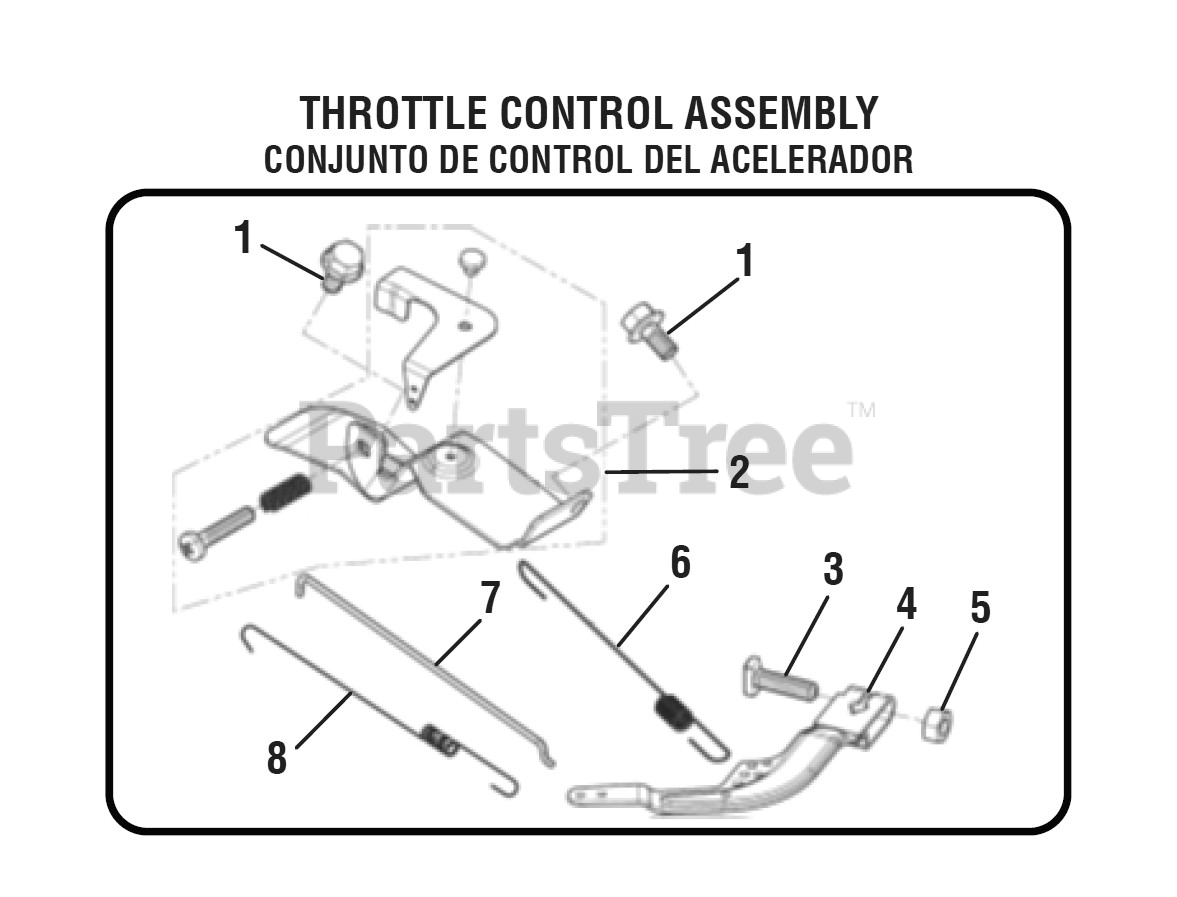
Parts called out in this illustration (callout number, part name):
2	Throttle Control Assembly
3	Governor Support Bolt
4	Governor Support Assembly
6	Governor Spring
7	Governor Rod
8	Throttle Valve Return Spring
